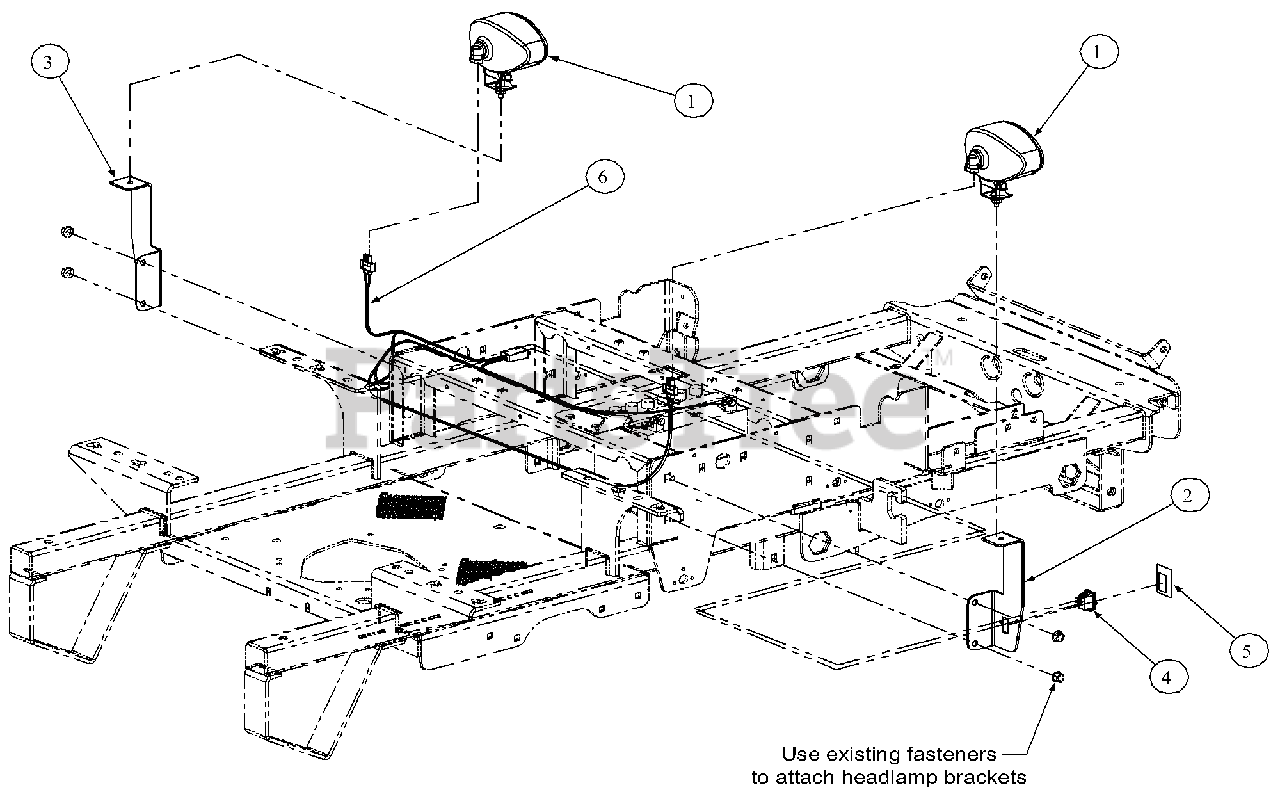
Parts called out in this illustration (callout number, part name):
1	Oval Work Lamp
2	Right Hand Lamp Bracket
3	Left Hand Lamp Bracket
4	Switch
5	Head Lamp On/Off Label
6	Wire Harness Assembly
